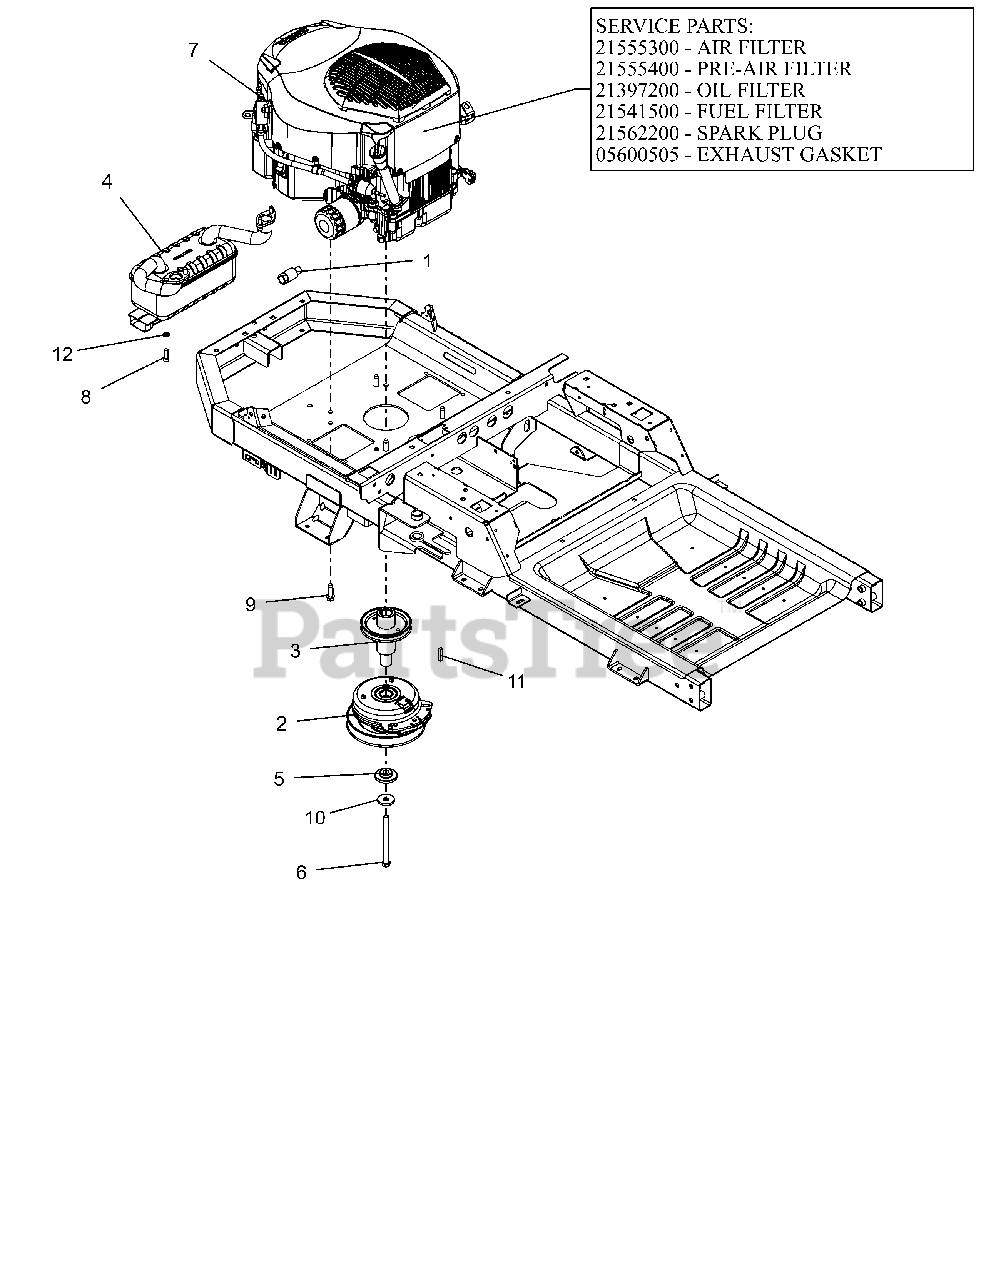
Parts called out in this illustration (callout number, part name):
1	DRAIN, OIL
2	CLUTCH,105FTLB MONOPOLE 6.83"
3	WLDMT, DRIVE SHEAVE (LG XL)CZC
4	MUFFLER, KOHLER
5	BSHG-FLG .469X1.06X.574X2.0
6	BLT-HEX.438-20X5 GR8 YZ NYTORQ
7	ENGINE,KOHLER TWIN 25 PRO W/SC
7	AIR FILTER, KOHLER
7	PRE CLEANER, KOHLER
7	FILTER, OIL - KOH CV20
7	FILTER, FUEL
7	PLUG, SPARK (RFI)
7	GASKET, MUFFLER KOHLER TWIN
8	SCR, SKH .312-18X.875 GR8 ZCC
9	SCR,TAP .375-16X1.25HWH TR ZCC
10	WASHER, 7/16" SPRING DISK
11	KEY-SQ .25 X 1.25 X .25 SAE
12	WSHR,LK-REG .312X.078 ZCC
